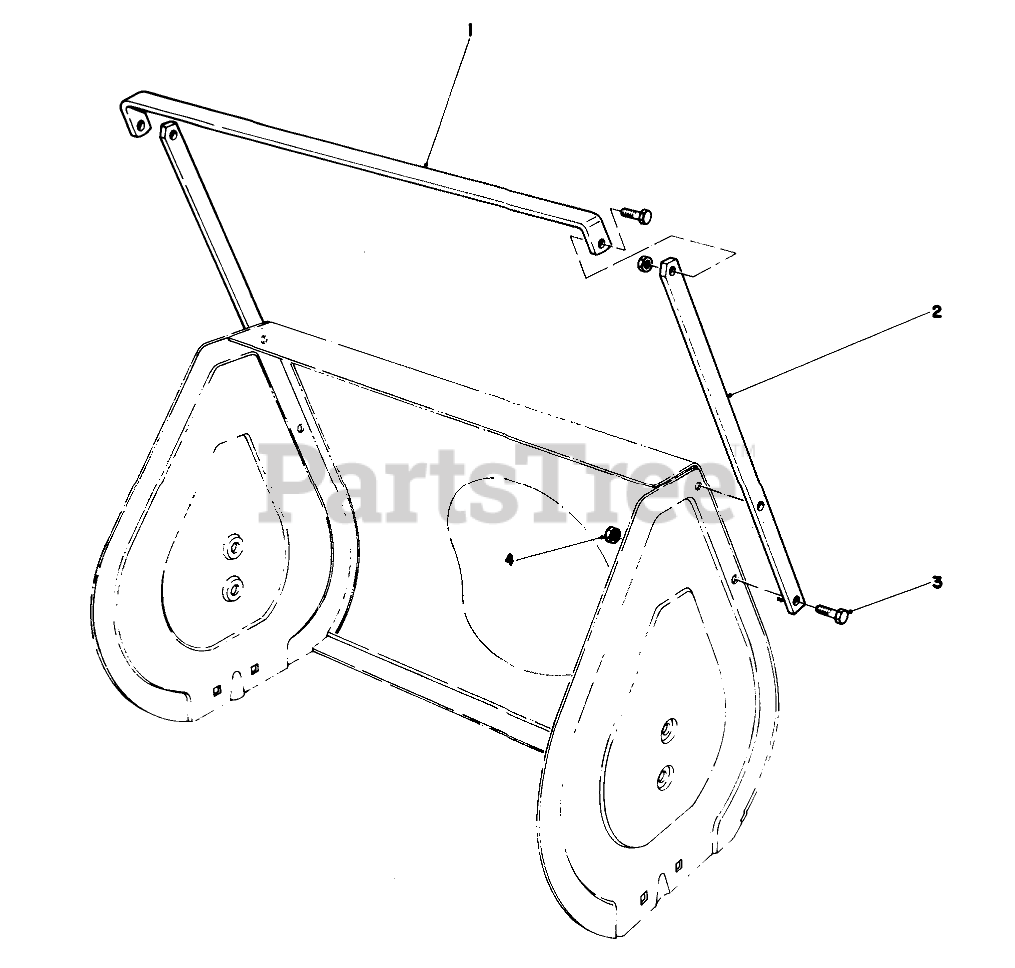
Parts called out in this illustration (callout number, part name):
1	Drift Breaker-Top
2	Drift Breaker-Side
3	SCREW-HH
4	NUT-LOCK, NI
